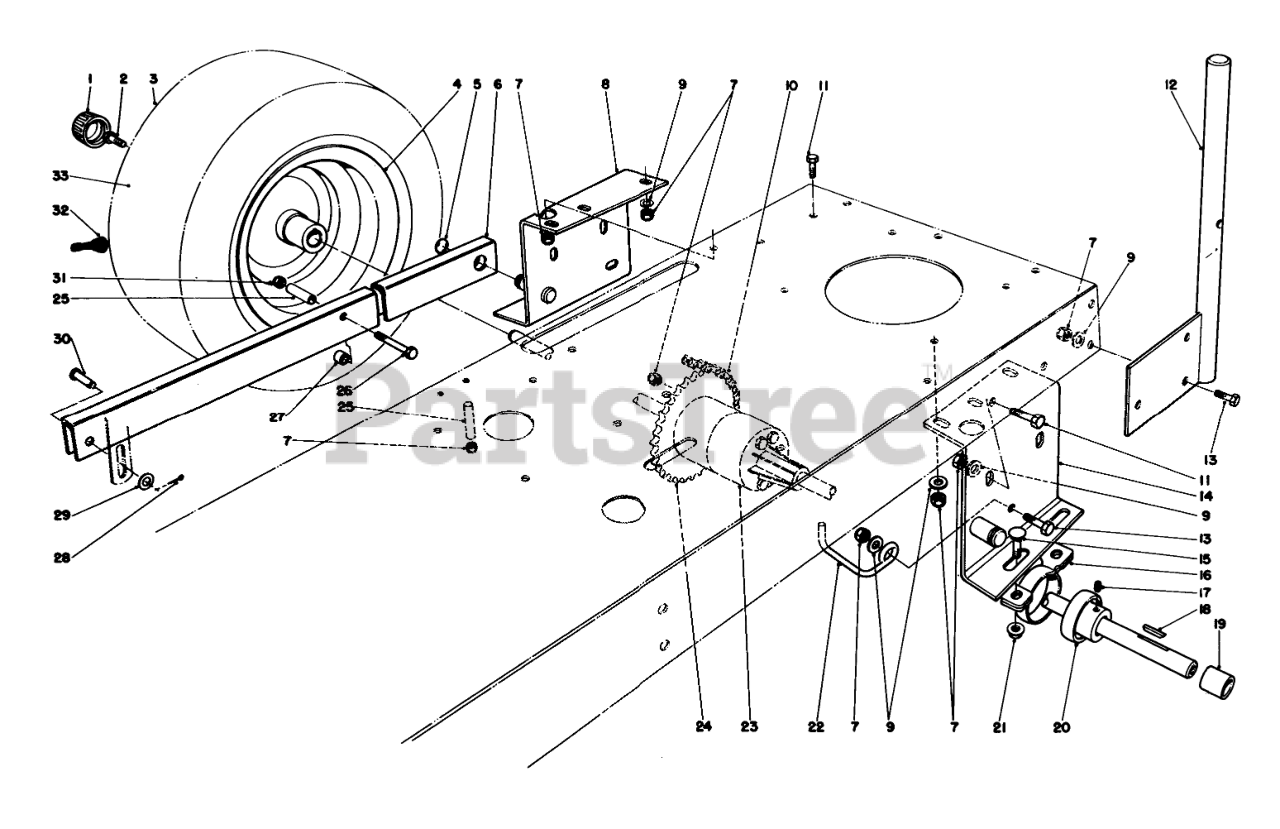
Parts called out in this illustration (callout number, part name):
1	Hub Cap
2	CAPSCREW 3/8 16 3/4
3	Tire
4	REAR RIM
5	E-RING
6	REAR SUSP ARMR
7	NUT-LOCK, NI
8	Support-Rear Axle R.H.
9	Washer
10	Chain
11	SCREW-HH
12	Stand Bar
13	SCREW-HH
14	Support-Rear Axle L.H.
15	SCREW-CARR
16	RTNR-PILLOW BLK
17	SCREW-SET, HSH
17	SCREW-SET
19	REAR AXLE SPACER
20	Bearing-Self Aligning (Incl. Ref. #17)
21	NUT-HF
22	BELT GUIDE
23	Differential
24	Sprocket Differential
25	OUTER TUBE SPACER
26	SCREW-HH
27	INNER TUBE SPACER
28	PIN-COTTER
29	WASHER-FLAT
30	PIN-CLEVIS
31	NUT-LOCK, CONE
32	STEM-VALVE
33	TUBE-INNER
